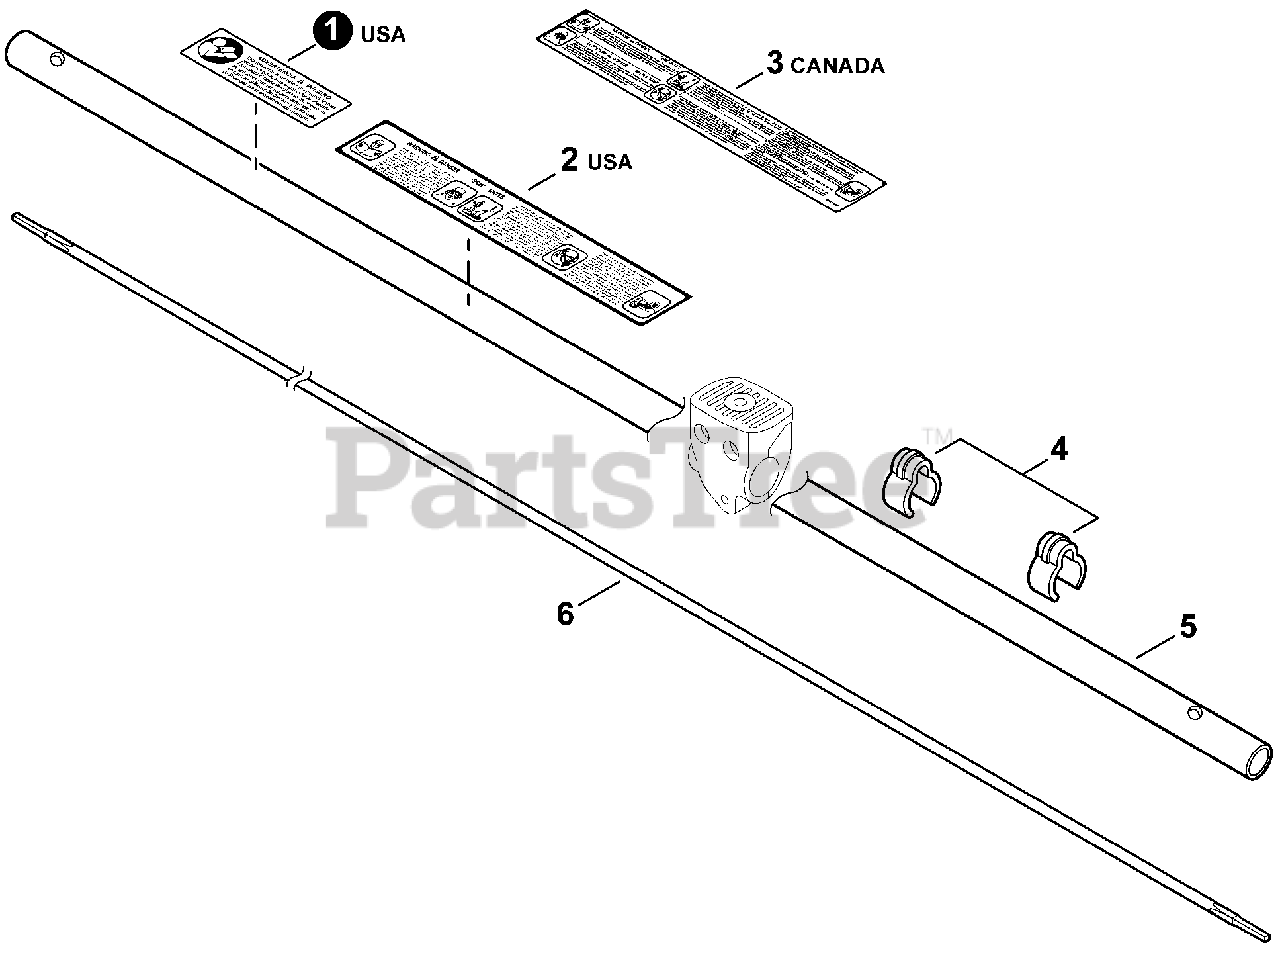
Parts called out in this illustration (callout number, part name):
1	LABEL, CAUTION
2	LABEL, CAUTION
3	LABEL, CAUTION
4	CLIP 28MM
5	PIPE, MAIN
6	DRIVESHAFT
